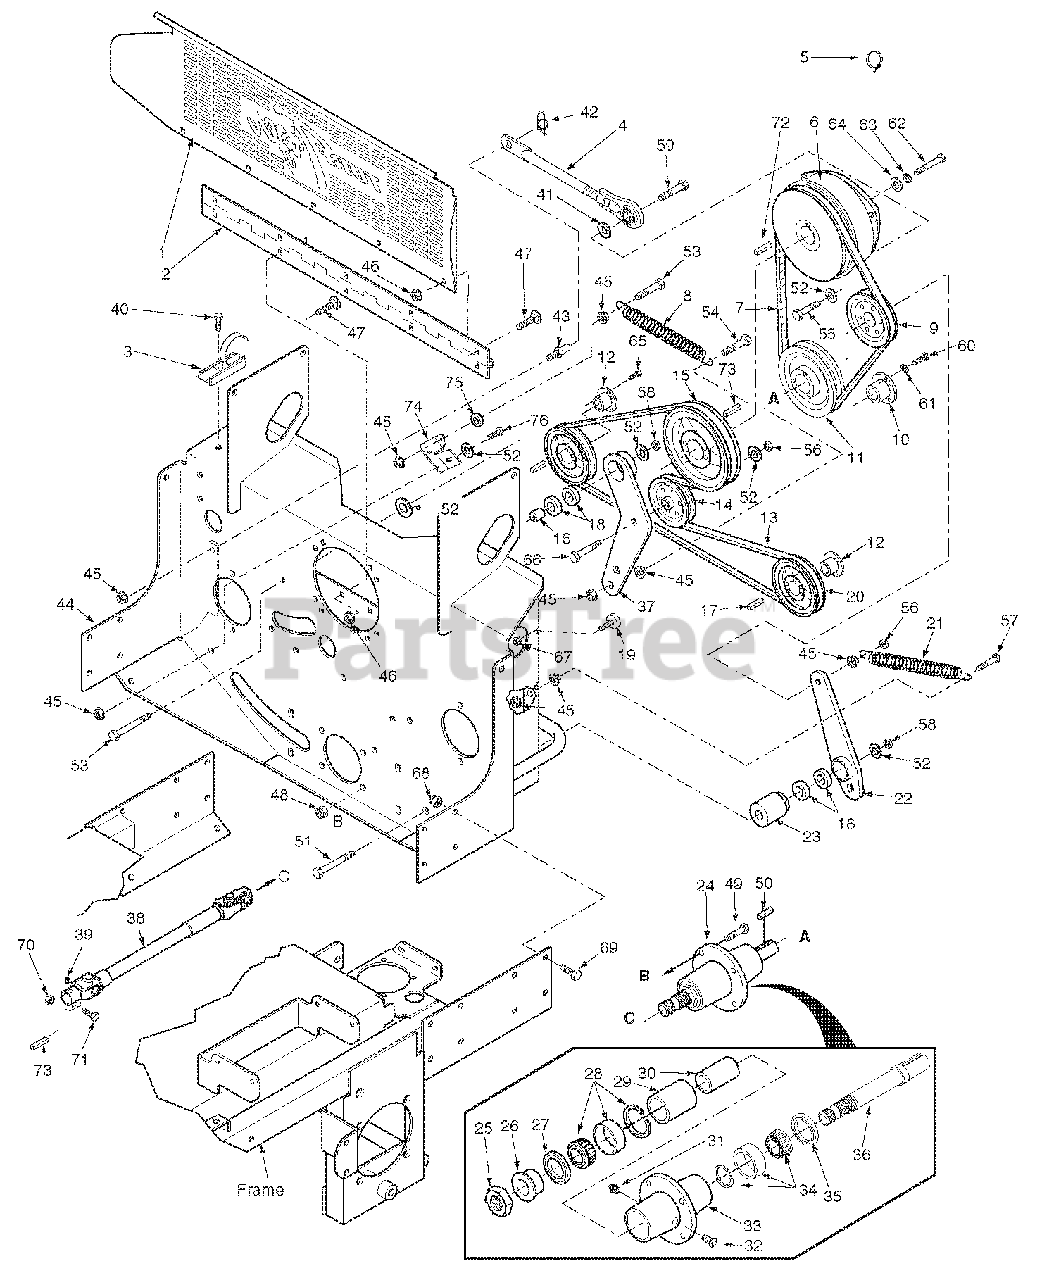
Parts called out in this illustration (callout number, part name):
1	Belt Guard, Rear
2	Hinge, Belt Guard
3	Latch, Hood
4	Rod Assembly, Clutch Anti-Rotation
5	Clamp, Cable
6	Clutch, Ogura GT-3.5
7	Belt, Deck Drive
8	Spring, Transmission Idler
9	Pulley, Idler 5" Dia.
10	Tapered Hub, 1" Bore
11	Pulley, 6.70" Tapered Bore
12	Tapered Hub, 17mm Bore
13	Belt, Pump Drive STT
14	Pulley, Idler 4" Dia.
15	Pulley, 4.55" Dia.-1.125" Bore
16	Spacer, Idler Bearing
17	Key, 5.0 x 5.0 x 25mm
18	Ball Bearing
19	Bumper, Rubber
20	Pulley, 6.35" O.D.
21	Spring, PTO
22	Idler Arm Weldment, PTO Drive
23	Pivot, Idler PTO
24	Spindle Assembly, Deck Drive
25	Nut, 1.06"-18 Thread
26	Spindle Bushing, Bottom
27	Seal, 2.0" OD x 1.625" Bore
28	Roller Bearing Tapered
29	Spacer, Outside
30	Spacer, Inside
31	Grease Fitting, 1/4-28
32	Relief Fitting
33	Spindle Housing
34	Roller Bearing Tapered
35	Seal, 2.0" OD x 1.5" Bore
36	Shaft, Deck Drive
37	Idler Arm Weldment, Pump Drive
38	Driveshaft (Air-Cooled Engine)
39	Set Screw, 3/8-16 x 3/4" Torx Socket
40	Screw, #10-32 x .56"
41	Flatwasher, 3/8 (.391 x .938 x .105")
42	Pin, Rue Cotter 3/8" Dia.
43	Stud, Anti Rotation
44	Pump Mounting Plate Weldment (STT-21CH-LP)
45	Nut, Serrated Flange 3/8-16
46	Nut, Serrated Flange 1/4-20
47	Bolt, Carriage 1/4-20 x 1/2"
48	Nut, Elastic Stop 5/16-18
49	Bolt, Hex Head 5/16-18 x 1-3/4"
50	Key, 1/4 x 1/4 x 1-1/2"
51	Bolt, Hex Head 3/8-16 x 4-1/2" Black
52	Washer, 3/8" Hardened
53	Bolt, Hex Head 3/8-16 x 1-3/4" Black
54	Bolt, Hex Head 3/8-16 x 1-1/2" Black
55	Bolt, Hex Head 3/8-16 x 2-1/2"
56	Nut, Center Lock 3/8-16
57	Bolt, Hex Head 3/8-16 x 1-1/2" Black
58	Nut, Elastic Stop 3/8-16
59	Bolt, Hex Head 3/8-16 x 2"
60	Bolt, Hex Head 1/4-20 x 1-3/8"
61	Lockwasher, 1/4" Spring
62	Bolt, Hex Head 7/16-20 x 2-1/2" UNF
63	Lockwasher, 7/16" Spring
64	Flatwasher, 7/16 (.469 x 1.75 x .25")
65	Bolt, Hex Head 1/4-20 x 1"
66	Bolt, Hex Head 3/8-16 x 1-3/4"
67	Nut, Serrated Flange 5/16-18
68	Nut, Elastic Stop 3/8-16
69	Bolt, Hex Head 3/8-16 x 1"
70	Nut, Center Lock 3/8-16
71	Bolt, Hex Head 3/8-16 x 1-3/4"
72	Key, 1/4 x 1/4 x 2-1/4"
73	Key, 1/4 x 1/4 x 1"
74	Bracket
75	Spacer
76	Bolt, Hex Head 3/8-16 x 1"
